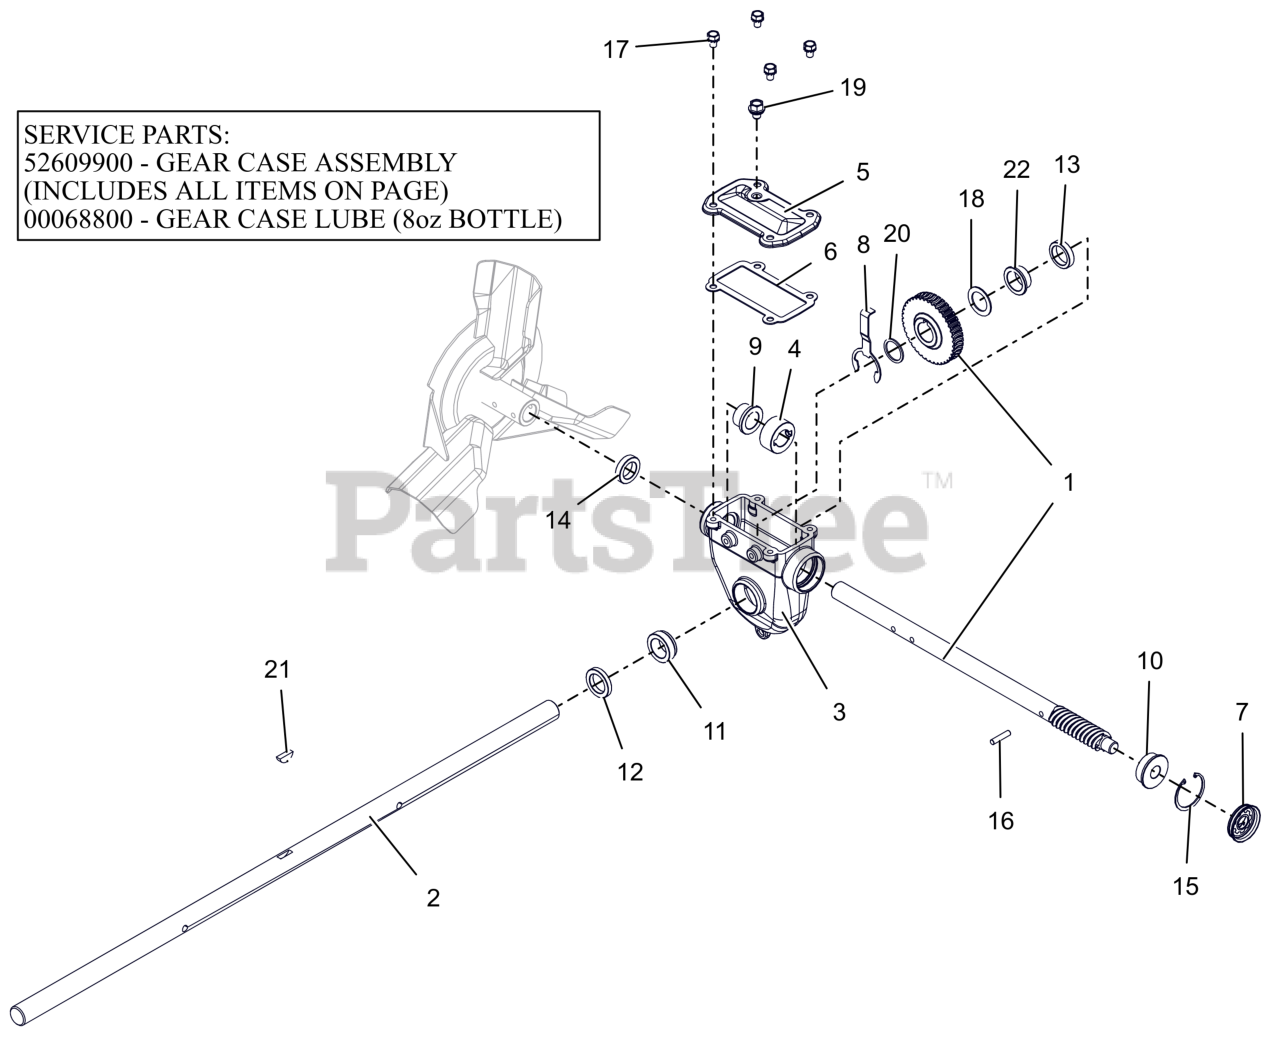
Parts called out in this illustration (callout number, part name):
1	ASSY, WORM SHAFT & GEAR
2	SHAFT, RAKE-36"
3	GEARCASE, LARGE MACHINED
3	GEAR CASE, 36" IRON PRO TOP-LD
3	ARIENS L3 LUBE, 8 OZ BOTTLE
4	THRUST COLLAR, .875"ID SLIPFIT
5	COVER, TOP - LARGE IRON
6	GASKET, TOP - LARGE GEARCASE
7	COVER, GEAR CASE 1.75"
8	BUSHING RETAINER, LARGE
9	BSHG-FLG .879X1.128X.75X1.45
10	BSHG-FLG .628X1.503X.58X1.725
11	BSHG-FLG LARGE, RIGHT
12	SEAL-OIL .999X1.500X.250 TBC29
13	SEAL-OIL .999X1.375X.312 TBC29
14	SEAL-OIL .873X1.375X.312 TBC29
15	RG-RTNG-INT 1.750X.062
16	PIN-STR .250X1.12 6150
17	BLT, SEMS .31-18X.50 G5 ZCC
18	WSHR, FLT 1.010X1.505X.062 ZCC
19	SCR, .380-15X.500 W/SEAL WASHER
20	WSHR, FLT 1.010X1.250X.068 ZCC
21	KEY-WDRF .25X.875 HRD #A
22	BSHG-FLG 1.006X1.128X.555X1.45
